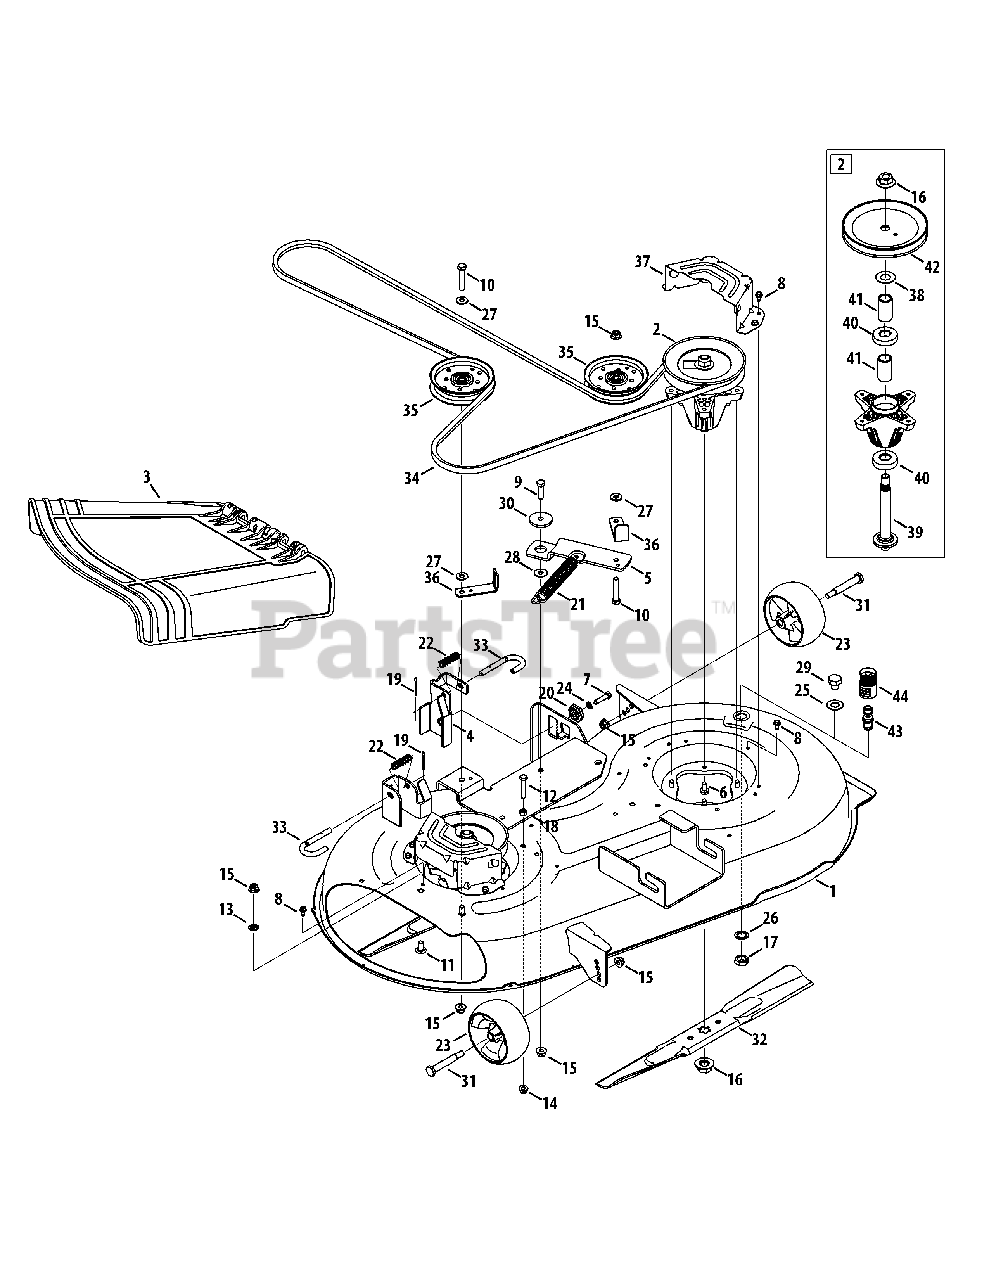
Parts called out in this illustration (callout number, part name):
1	Deck Housing
2	Spindle Assembly w/pulley
3	Discharge Chute Assembly
4	Deck Lift Bracket
6	Hex Washer Head Screw, 5/16-18 x .750
7	Hex Cap Screw, 5/16-18 x 1.25
8	Hex Washer Head Screw, 1/4-20 x .5
9	Hex Cap Screw, 3/8-16 x 1.25
10	Hex Cap Screw, 3/8-16 x 2.00
11	Carriage Screw, 3/8-16 x .75
12	Hex Cap Screw, 5/16-18 x 1.75
13	Push Nut, 3/8
14	Flange Lock Nut, 5/16-18
15	Flange Lock Nut, 3/8-16
16	Hex Flange Nut, 5/8-18
17	Hex Nut, M16-1.5
18	Hex Nut, 5/8-18
19	Cotter Pin, 1/8 x 1.25
20	Deck Adjustment Gear
21	Extension Spring, .94 Dia. x 6.74
22	Compression Spring, .535 x 1.751
23	Deck Ball Wheel, 5.0
24	Lock Washer, 5/16
25	Flat Washer, .64 x 1.24 x .06
26	Internal Tooth Lock Washer, 5/8
27	Flat Washer, .385 x .870 x .092
28	Flat Washer, .385 x 1.00 x .030
29	Bolt, M16 x 1.5
30	Shoulder Spacer, .884 x .190
31	Shoulder Screw, .5 x 2.5 x 3/8-16
32	Blade, 2 in 1, 21.23
33	Deck Hanger Rod
34	V-Belt
35	Idler Pulley, 4.25 Dia.
36	Bracket, Belt Guard
37	Belt Cover
38	Washer, .760 x 1.50 x .030
39	Spindle Shaft
40	Ball Bearing
41	Spacer, .792 x 1.060 x 1.860
42	Deck Pulley
43	Deck Water Nozzle
44	Water Nozzle Adapter
